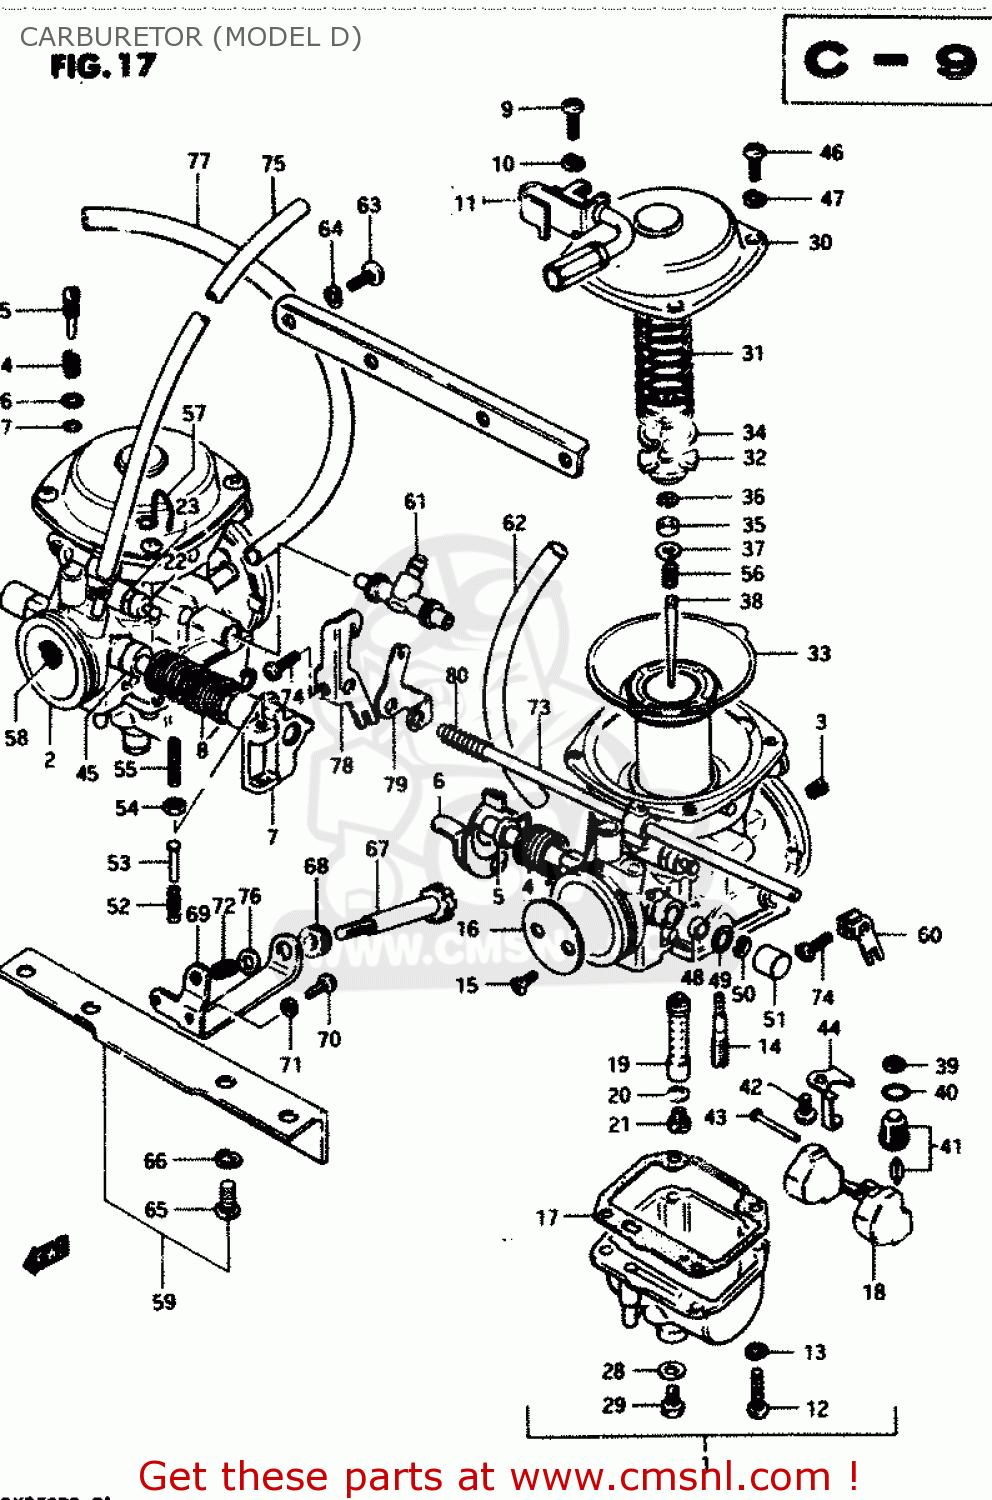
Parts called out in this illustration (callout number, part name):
1	CARBURETOR, LH
2	CARBURETOR, RH
3	JET,MAIN(135)
4	SPRING
5	RING
6	SHAFT ASSEMBLY
7	SHAFT ASSEMBLY
8	SPRING
9	SCREW
10	LOCK WASHER
11	BRACKET,THROTTLE CABLE
12	SCREW
13	LOCK WASHER
14	JET
15	SCREW
16	VALVE,THROTTLE
17	GASKET,FLOAT CAHMBER (NAS)
18	FLOAT
19	JET,NEEDLE(P-1)
20	WASHER,NEEDLE NOZZLE
21	JET,MAIN(117.5)
22	CAP,PLUNGER
23	O-RING
24	SPRING
25	SCREW,PILOT AIR
26	GASKET
27	O-RING
28	GASKET (NAS)
29	PLUG,DRAIN
30	COVER,DIAPHRAGM
31	SPRING
32	HOLDER,GUIDE
33	DIAPHRAGM
34	E RING
35	RING
36	CLIP,NEEDLE
37	WASHER
38	NEEDLE,JET
39	FILTER
40	O RING
41	VALVE ASSEMBLY,NEEDLE
42	SCREW 4X6
43	PIN,FLOAT
44	PLATE,NEEDLE VALVE FITING
45	RING,THROTTLE VALVE
46	SCREW
47	LOCK WASHER
48	SEAL
49	GASKET,THROTTLE SHAFT (NAS)
50	E RING
51	CAP
52	SPRING,THROTTLE SCREW
53	PIN,THROTTLE LEVER
54	NUT
55	SCREW
56	SPRING
57	CLIP,HOSE
58	FILTER NET ASSEMBLY
59	CARBURETOR ASSEMBLY
60	LEVER
61	NIPPLE,CARBURETOR
62	HOSE
63	SCREW
64	LOCK WASHER
65	SCREW
66	LOCK WASHER
67	SCREW,THROTTLE STOP
68	BUSHING,THROTTLE ADJUSTER
69	BRACKET
70	SCREW
71	LOCK WASHER
72	SPRING
73	SHAFT,STARTER
74	SCREW,THROTTLE ADJUST
75	HOSE
76	WASHER
77	HOSE
78	LEVER,STARTER
79	SPACER,STARTER LEVER
80	SPRING
